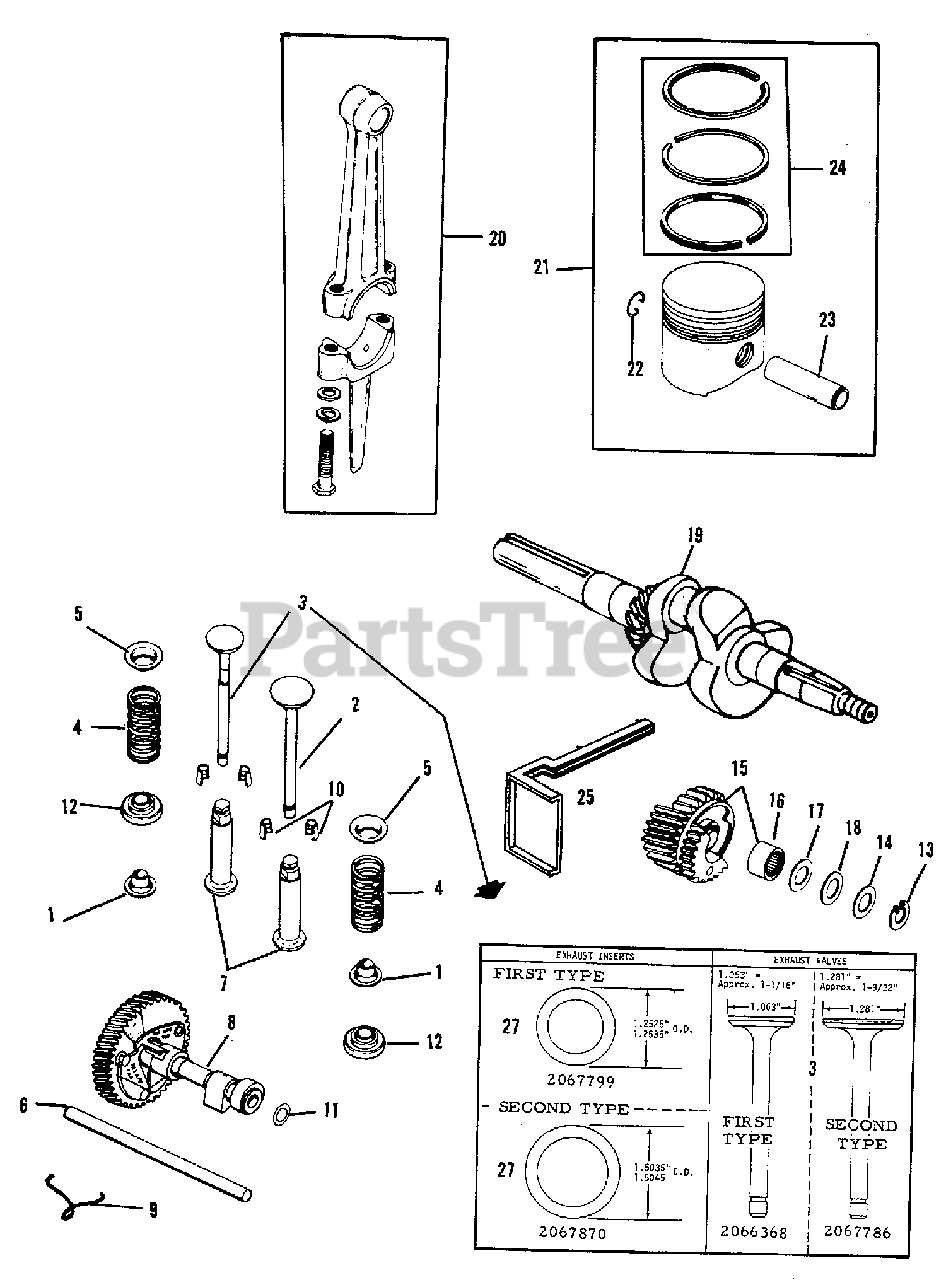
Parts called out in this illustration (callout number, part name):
1	RETAINER, Spring (Not for 16 HP)
2	VALVE, Intermediate (10 HP)
2	VALVE, Intermediate (14 & 16 HP)
3	VALVE, Exhaust (10 HP)
3	VALVE, Exhaust (1-1/16" O.D. For 1st Type 14 HP)
3	VALVE, Exhaust (1-9/32" O.D. For 2nd Type 14 & All 16 HP)
4	SPRING, Valve (10 HP)
4	SPRING, Valve (14 & 16 HP)
5	RETAINER, Upper String
6	PIN, Camshaft
7	TAPPET ASSEMBLY
8	CAMSHAFT, 10 hp & 14 hp (Includes SPRING)
8	CAMSHAFT, 16 HP (Includes SPRING)
9	SPRING, Actuating
10	KEEPER, Valve Keeper (In Pairs)
11	SPACER, Camshaft .005 (Use As Required)
11	SPACER, Camshaft .010 (Use As Required)
12	ROTATOR, Valve
15	GEAR ASSEMBLY, (Includes Item 16)
16	BEARING, Needle
17	SPACER, 10 & 14 HP
18	SPACER, 10 & 14 HP
18	SPACER, 16 HP
19	CRANKSHAFT, 10 HP
19	CRANKSHAFT, 14 HP
19	CRANKSHAFT, 16 HP
19	KEY, Crankshaft
20	CONNECTING ROD, Standard (10 HP)
20	CONNECTING ROD, Standard (14 HP)
20	CONNECTING ROD, Standard (16 HP)
20	CONNECTING ROD, .010 u/s (10 HP)
20	CONNECTING ROD, .010 u/s (14 HP)
20	CONNECTING ROD, .010 u/s (16 HP)
20	LOCKWASHER, 3/8
21	PISTON, Standard (10 HP)
21	PISTON, .010 (10 HP)
21	PISTON, .020 (10 HP)
21	PISTON, .030 (10 HP)
21	PISTON, Standard (14 HP)
21	PISTON, .010 (14 HP)
21	PISTON, .020 (14 HP)
21	PISTON, .030 (14 HP)
21	PISTON, Standard (16 HP)
21	PISTON, .010 (16 HP)
21	PISTON, .020 (16 HP)
21	PISTON, .030 (16 HP)
22	RETAINER, Pin (10 HP)
22	RETAINER, Pin (14 & 16 HP)
23	PIN, Piston (10 HP)
23	PIN, Piston (14 HP)
23	PIN, Piston (16 HP)
24	RING SET, Standard (10 HP)
24	RING SET, .010 (10 HP)
24	RING SET, .020 (10 HP)
24	RING SET, .030 (10 HP)
24	RING SET, Standard (14 HP)
24	RING SET, .010 (14 HP)
24	RING SET, .020 (14 HP)
24	RING SET, .030 (14 HP)
24	RING SET, Standard (16 HP)
24	RING SET, .010 (16 HP)
24	RING SET, .020 (16 HP)
24	RING SET, .030 (16 HP)
25	TOOL, Guage (For Balance Weights On Chrankshaft Gear)
26	GUIDE, Valve
27	INSERT, Exhaust Valve (10 & 14 HP w/ 1-1/16 O.D. Exhaust Valve)
27	INSERT, Exahust & Intermediate Valve (Once Use As Exhaust Insert f/14 HP With 1-9/32" O.D. Exhaust Valve & 2 Used as Exhause & Intermediate On 16 HP)
